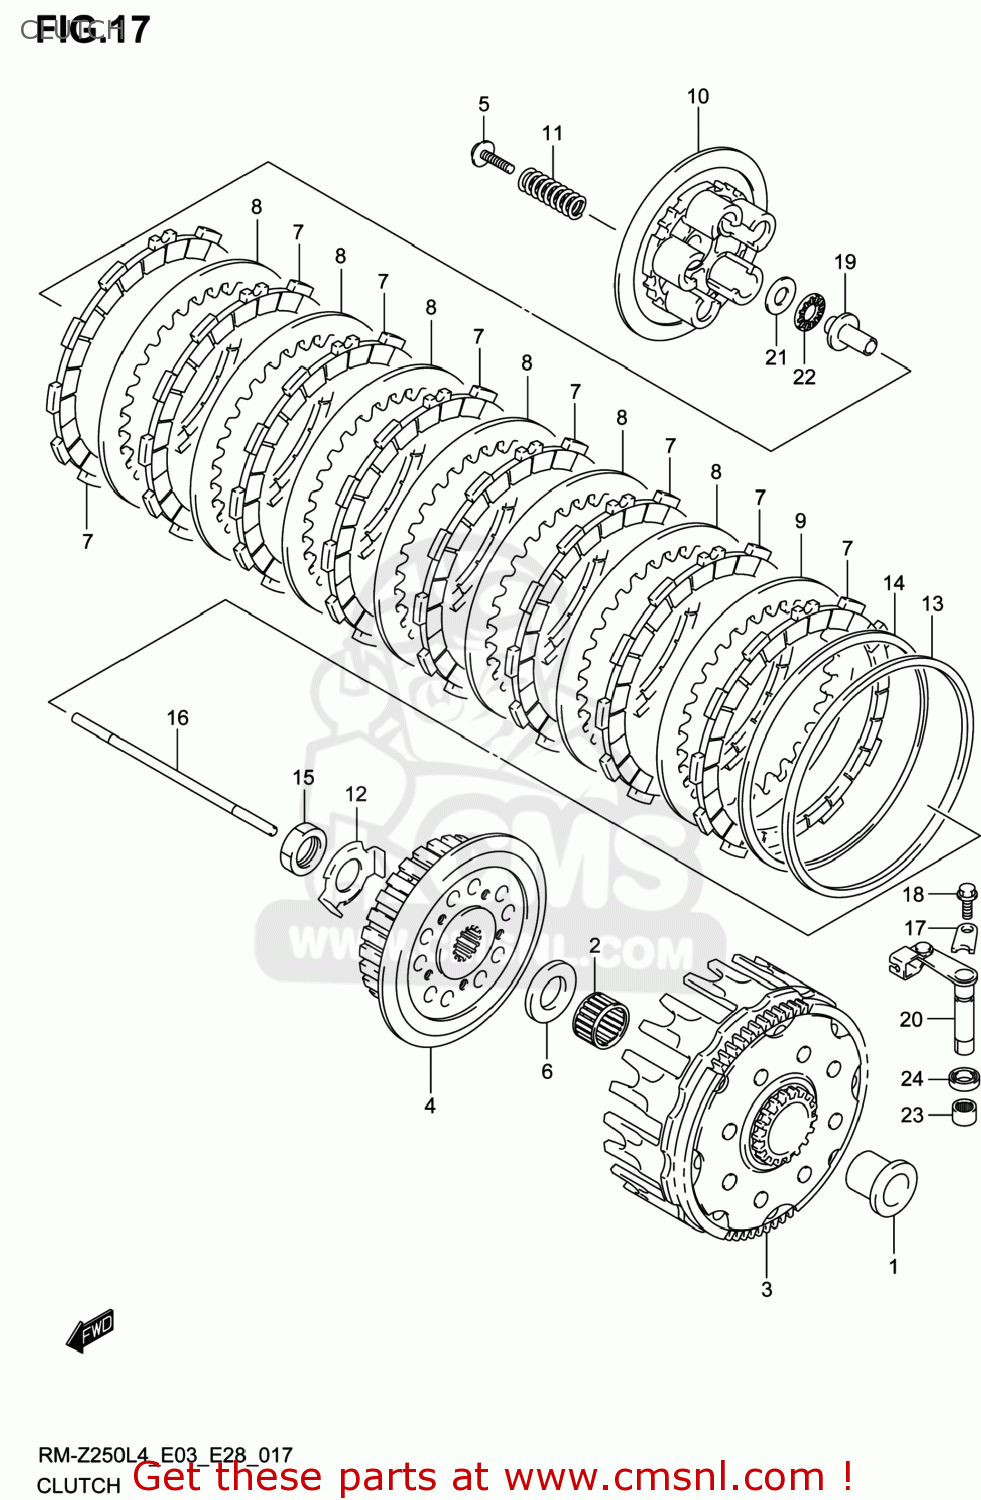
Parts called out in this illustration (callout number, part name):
1	SPACER,PRIMARY DRIVEN GEAR
2	BEARING(27X32X21.8)
3	GEAR ASSY,PRI DRIVEN
4	HUB,CLUTCH SLEEVE
5	BOLT,CLUTCH SPRING
6	WASHER(22X45X3)
7	PLATE,CLUTCH DRIVE NO.2 (NAS)
8	PLATE,CLUTCH DRIVEN (NAS)
9	PLATE,CLUTCH DRIVEN (NAS)
10	DISC,CLUTCH PRESSURE
11	SPRING,CLUTCH
12	WASHER,CLUTCH SLEEVE HUB LOCK
13	SEAT,CLUTCH PLATE WAVE WASHER
14	WASHER,CLUTCH PLATE
15	NUT
16	ROD,CLUTCH PUSH
17	RETAINER,CL RELEASE CAMSHAFT
18	BOLT(6X12)
19	PIECE,CLUTCH PUSH
20	CAMSHAFT,CLUTCH RELEASE
21	SHIM(12X26X0.8)
22	BEARING(12X26X2)
23	BEARING(10X14X10)
24	SEAL,OIL(10X17X5)
